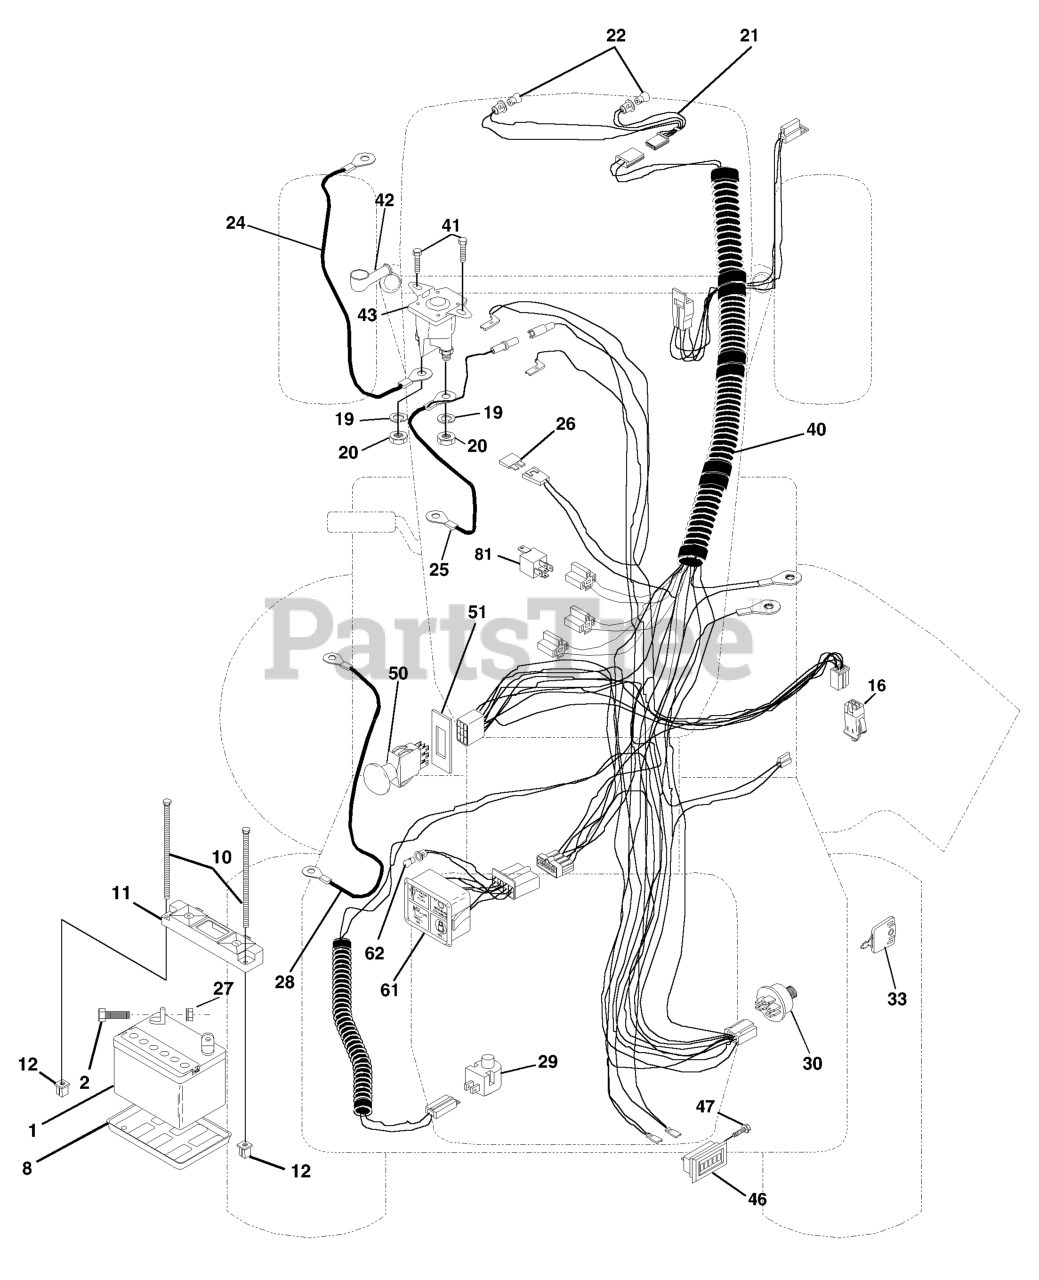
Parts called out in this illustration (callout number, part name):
1	BATTERY 12V .35 AMP
2	BOLT.HEX.1/4.X.3/4.DICHROMATE
8	BATTERY TRAY T
10	BOLT 1/4-20 X 7.5
11	BATTERY HOLDDOWN FRONT MOUNT
12	NUT, PUSH NYLON 1/4" BATTERY
16	SWITCH INTERLOCK
19	LOCKWASHER
20	NUT
21	HARNESS ASM, LIGHT W/4152J
24	CABLE, STARTER
25	CABLE, BATTERY
27	NUT
28	CABLE, GROUND
29	PLUNGER SWITCH (COLOR:OLIVE)
30	SWITCH IGN
33	KEY MLD GEN DELTA
40	HARNESS, IGN
41	SCREW
42	TERMINAL COVER
43	SOLINOID
46	HOUR METER T
47	Screw #10-24 x 1/2
50	SWITCH PTO 3 PDT
51	FRAME RETAINING RING
61	LIGHT PACKAGE
62	BULB LIGHT T
81	RELAY.ASSY.T
